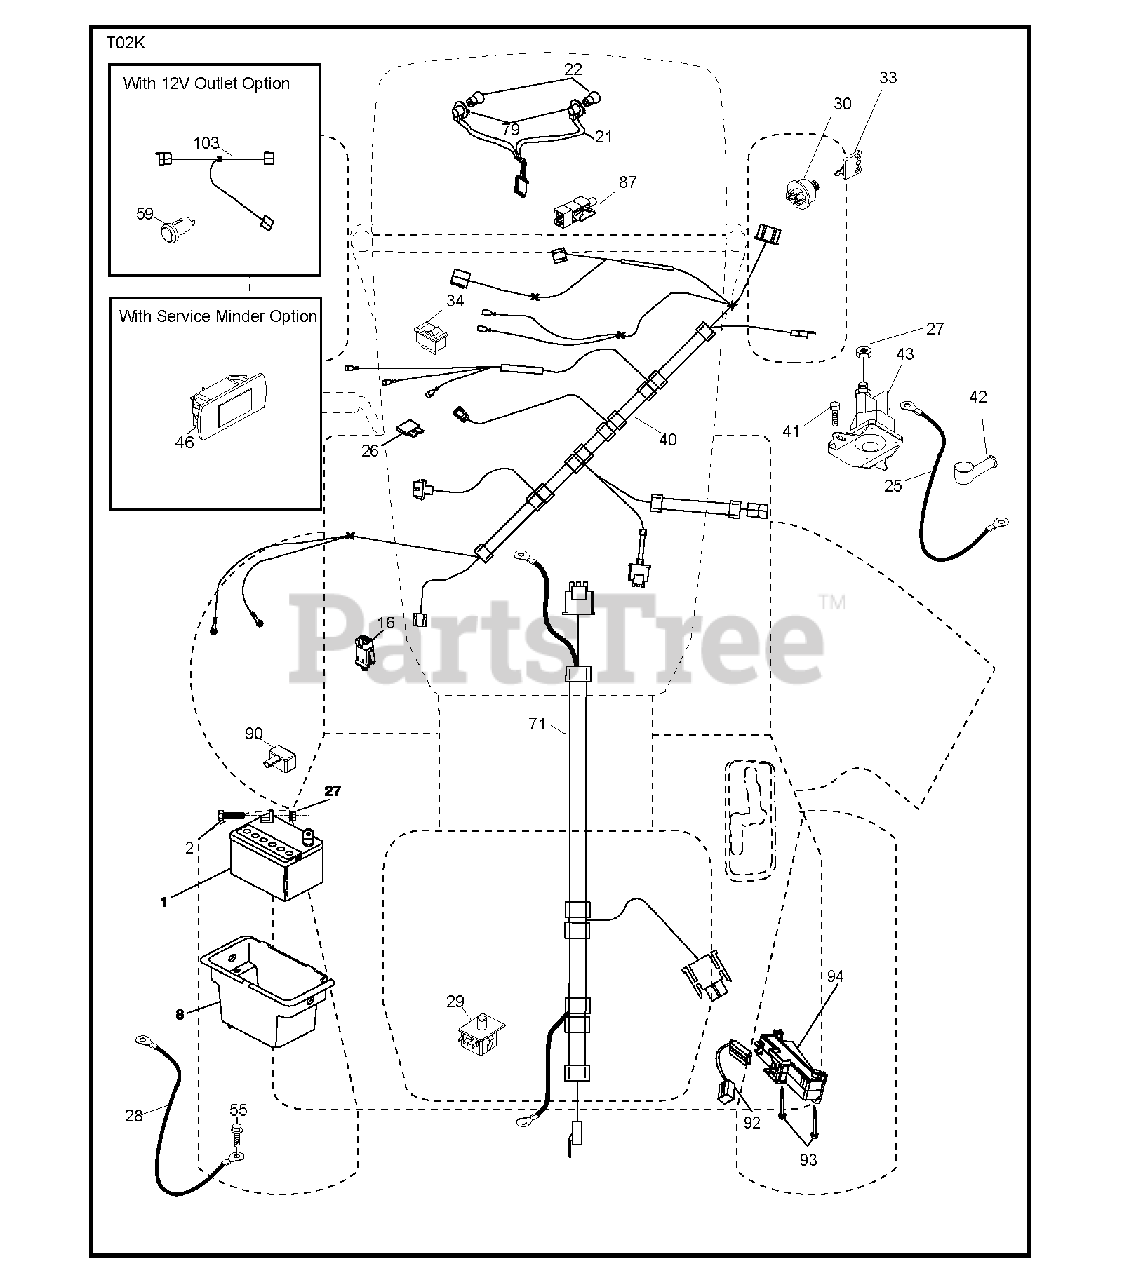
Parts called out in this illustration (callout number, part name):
1	REPL BY 532 12 38-99
2	BOLT.HEX.1/4.X.3/4.DICHROMATE
8	BOX.BATTERY.MNT.REAR.L
16	SWITCH INTERLOOK PUSH-IN
21	HARNESS ASSY LIGHT
22	LIGHTBULB
25	CABLE.STARTER.6GA.BL/RED.14.
26	FUSE 20AMP
27	NUT
28	CABLE.BLACK.18"REAR.BA
29	SWITCH.SEAT.DP W/RAMPS
30	SWITCH.IGN.DELTA.W.LGH.ROS
33	KEY.CHAIN.BLISTER.PACK.GEN.USA
34	SWITCH LT
40	HARNESS IGN. DASH
41	SCREW
42	TERMINAL COVER
43	SOLENOID.W/BRASS.PLUNGER
55	SCREW 5/16"
71	HARNESS.IGN.CHASS.TEX.REAR.BAT
79	BULB HOLDER ASM.
87	SWITCH.INTRLCK.CLUTCH.
90	COVER, TERMINAL BATTERY
92	HARNESS.PIGTAIL.CONSLE
93	SCREW.PLASTITE
94	MODULE.REVERSE.ROS
